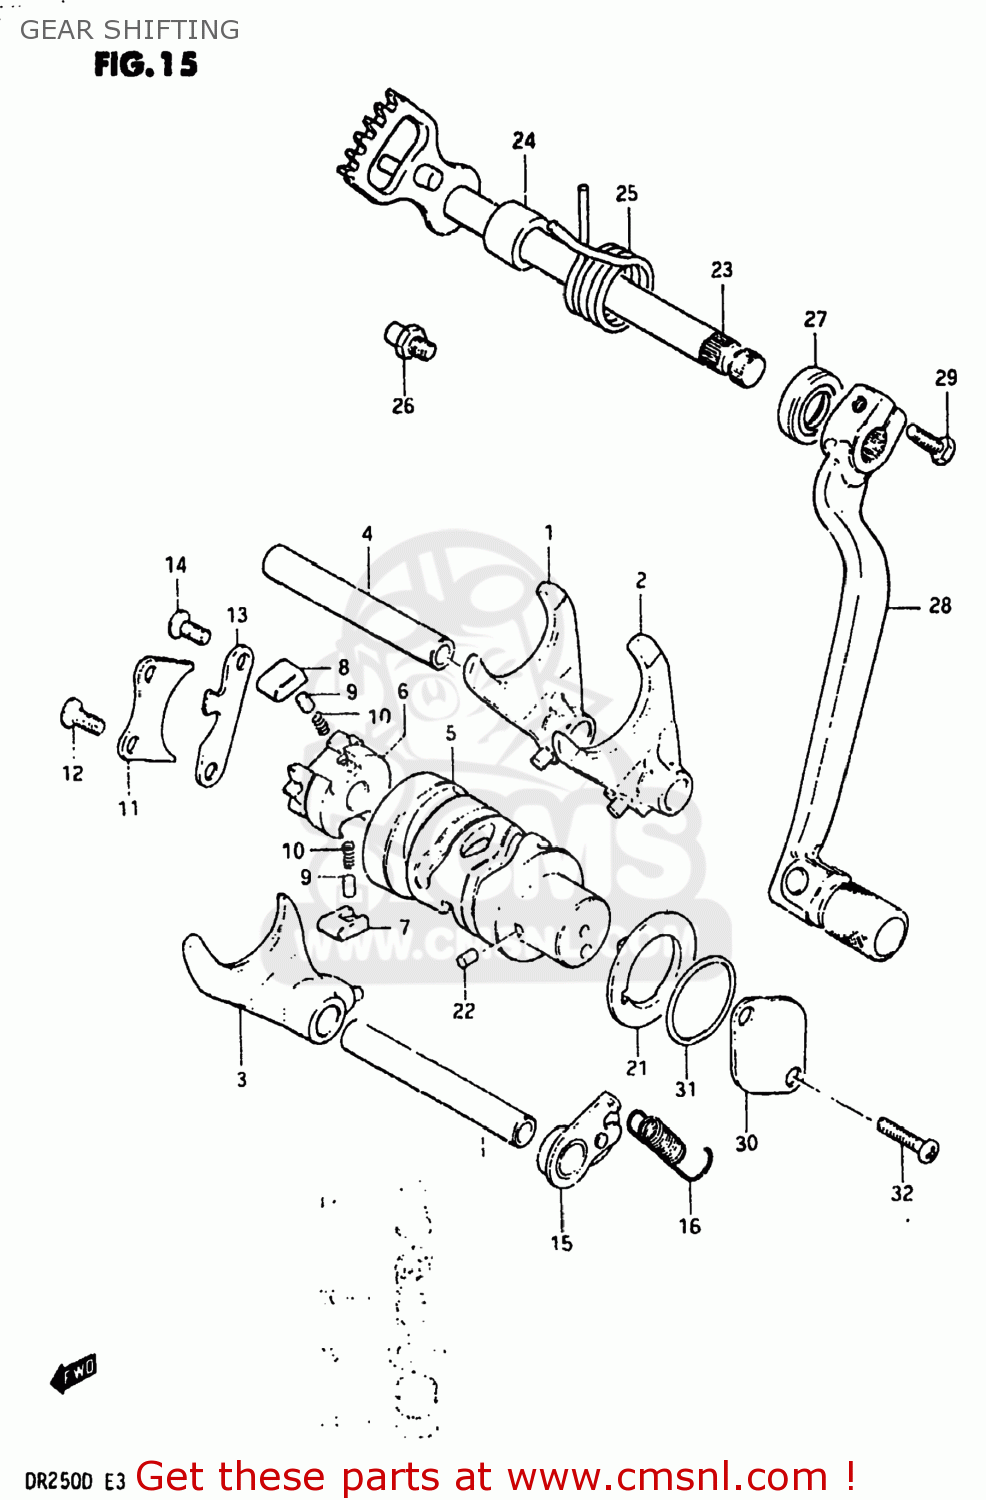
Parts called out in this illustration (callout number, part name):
1	FORK,GEAR SHIFT NO.1
2	FORK,GEAR SHIFT
3	FORK,GEAR SHIFT NO.3
4	SHAFT,GEAR SHIFT FORK
5	CAM,GEAR SHIFT
6	RETAINER,GEAR SHIFT CAM
7	PAWL,GEAR SHIFT NO.1
8	PAWL,GEAR SHIFT NO.2
9	PIN(5X8)
10	SPRING
11	LIFTER,GEAR SHIFT PAWL
12	SCREW
13	GUIDE,GEAR SHIFT CAM
14	SCREW
15	STOPPER,GEAR SHIFT CAM
16	SPRING
17	STOPPER,GEAR SHIFT CAM NO.2
18	PLUG (14X12)
19	GASKET(14X19.2X2) (NAS)
20	SPRING
21	PLATE,GEAR SHIFT CAM STOPPER
22	PIN 4X6
23	SHAFT,GEAR SHIFT
24	SPACER(12X20X15.3)
25	SPRING
26	STOPPER,GEAR SHIFT CAM
27	OIL SEAL
28	LEVER ASSY,GEAR SHIFT
29	BOLT
30	CAP,GEAR SHIFT CAM PIVOT
31	O-RING (D:2.4 ID:26.2)
32	SCREW
